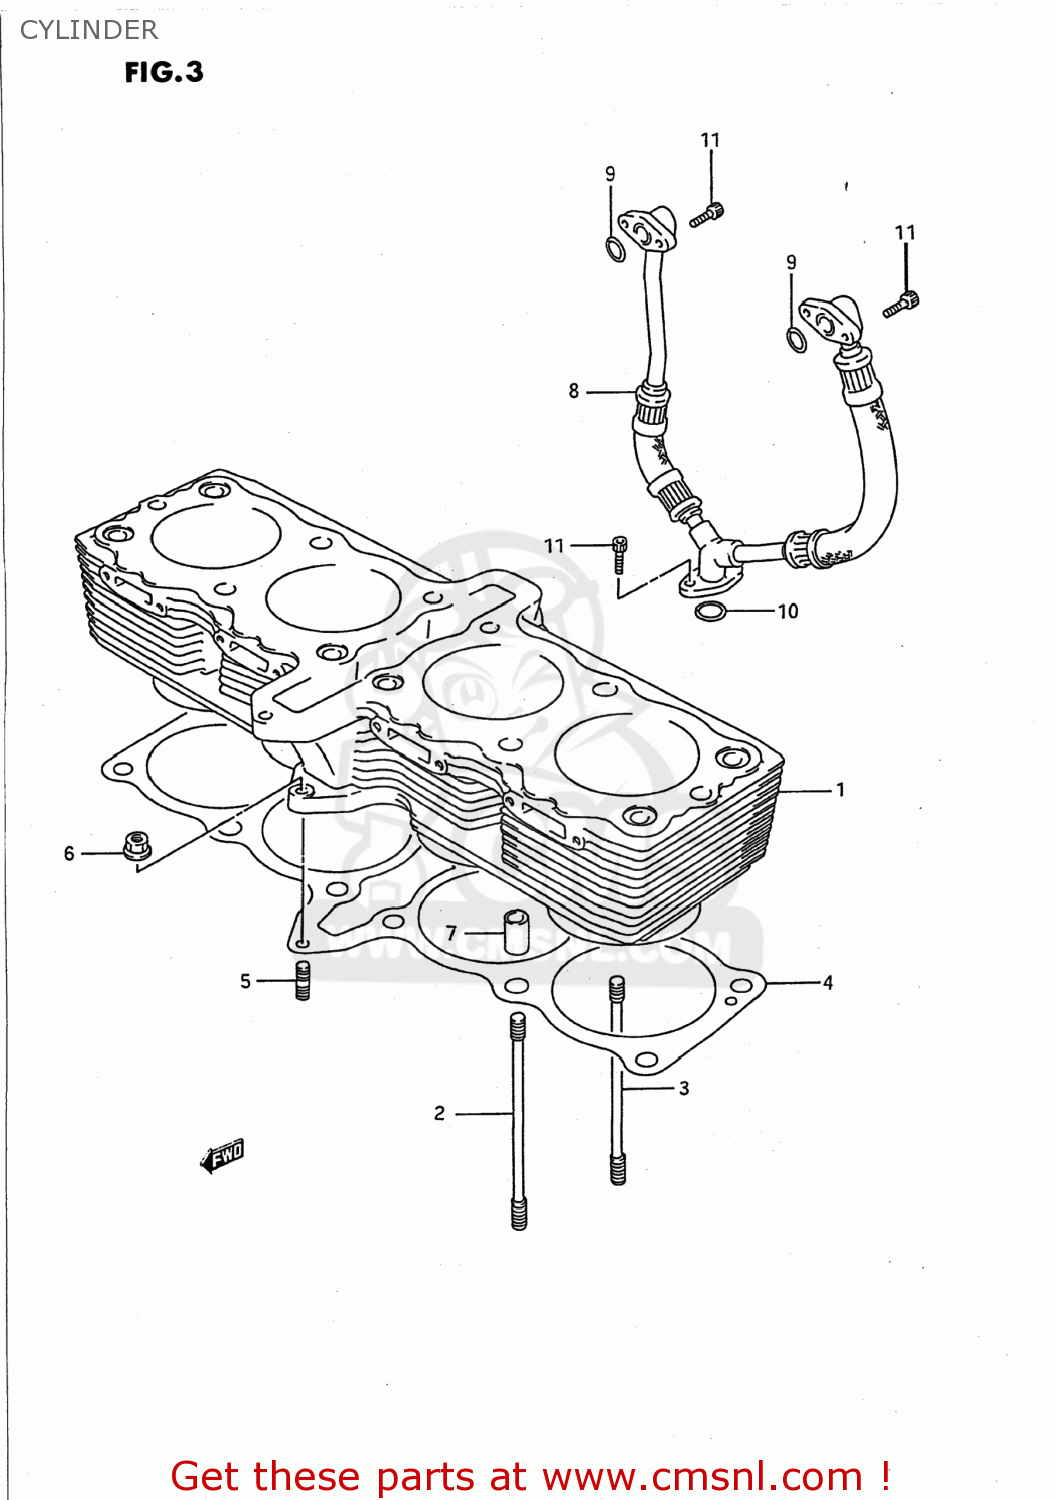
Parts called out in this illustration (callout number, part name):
1	CYLINDER
2	BOLT,STUD
3	BOLT,STUD
4	GASKET,CYLINDER (NAS)
5	STUD,M6X1X32
6	NUT
7	PIN
8	HOSE,OIL HEAD COOLER
9	O RING(D:2.5,ID:13.8)
10	O RING(D:2.4,ID:15.8)
11	BOLT
